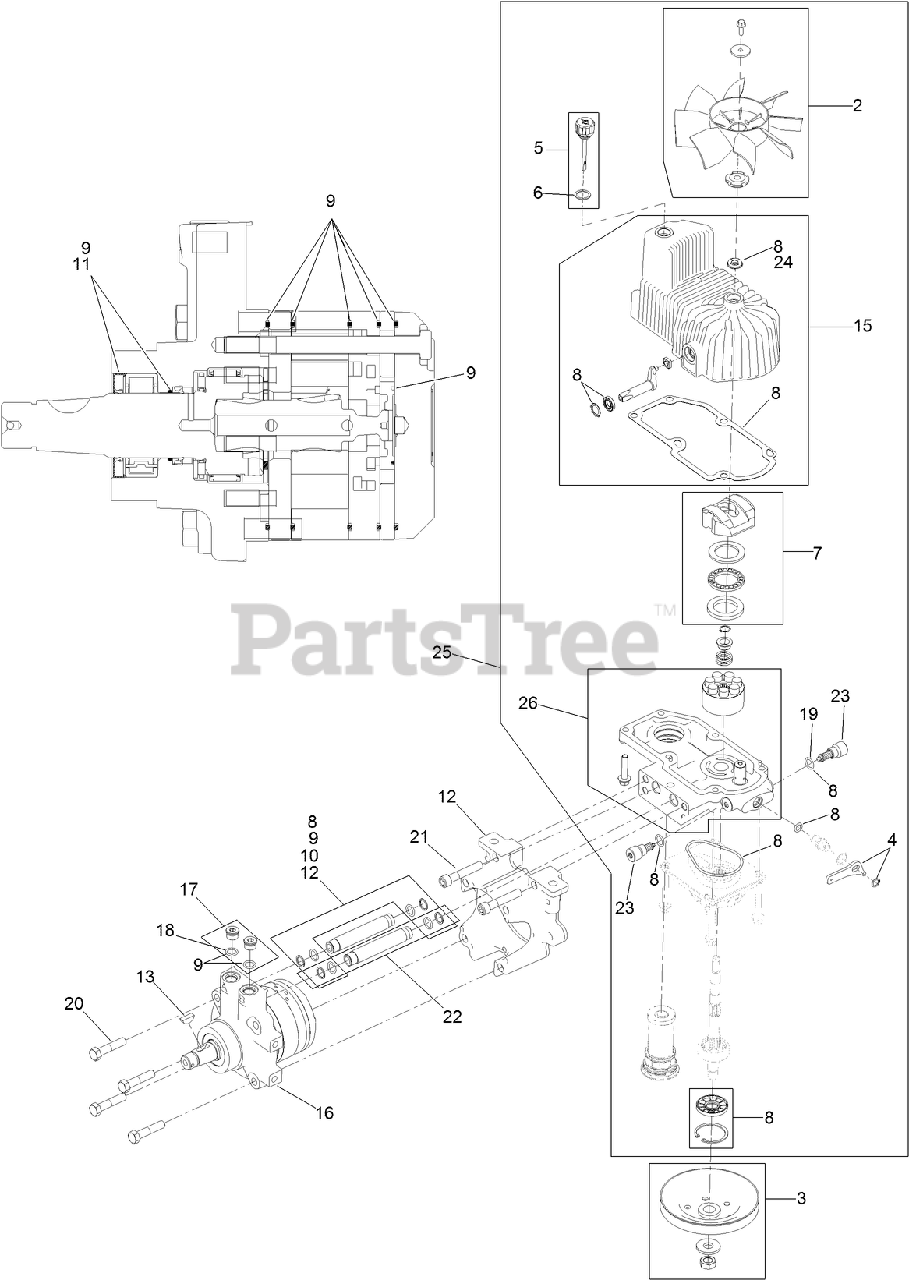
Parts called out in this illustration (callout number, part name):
2	FAN KIT
3	PULLEY KIT
4	HANDLE-BYPASS VALVE, HYDRO
5	DIPSTICK-HYDRO W/GASKET
6	GASKET-DIPSTICK, HYDRO
7	SWASH BLOCK KIT
8	PUMP SEAL KIT
9	MOTOR SEAL KIT
10	TUBE SEAL KIT
11	OUTPUT SHAFT SEAL KIT
12	NOSE CUP-UHT
13	KEY-WOODRUFF
15	HOUSING-HYDRO, LH
16	MOTOR-HYDRAULIC, LH 280CC
17	MAGNETIC PLUGS SERVICE KIT
18	O-RING
19	O-RING-CHECK VALVE
20	SCREW HH
21	SCREW-HSH
22	HYDRAULIC TUBE KIT
23	SHOCK VALVE, 16CC HYDRO
24	SEAL-FAN DRIVE
25	16CC LH PUMP SECTION KIT
26	16CC LH ROTATING GRP KIT
